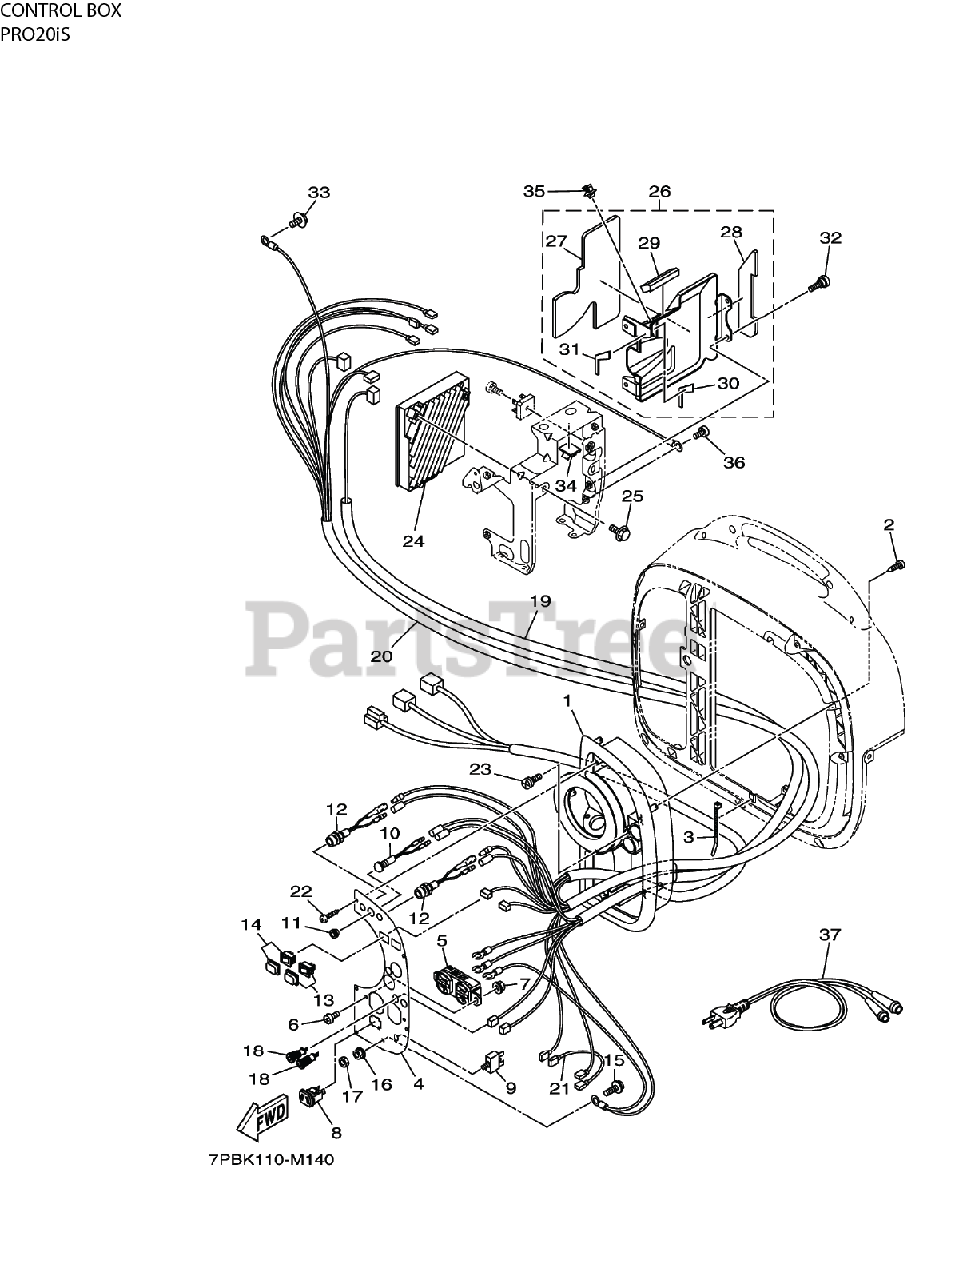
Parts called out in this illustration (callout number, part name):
1	HOUSING - CONTROL BOX COMP
2	SCREW - TAPPING
3	STRAP, CLAMP
4	PANEL, PLATE
5	REED, RECEPTACLE (P&S 5-20R)
6	SCREW - PAN HEAD
7	NUT, FLANGE
8	REED, RECEPTACLE COMP (DC 24V-12A)
9	BREAKER, CIRCUIT COMP (BA)
10	INDICATOR - PILOT LIGHT ASSEMBLY
12	INDICATOR, PILOT LIGHT
13	SWITCH, ENGINE STOP ASSEMBLY
14	SWITCH, ENGINE STOP ASSEMBLY
15	SCREW - BOLT
16	NUT, FLANGE
18	TERMINAL 1
19	HARNESS ASSEMBLY - WIRE
20	LEAD, WIRE
21	LEAD, WIRE 4
22	SCREW - TAPPING
23	SCREW - PAN HEAD
24	ECU, GENSET
25	SCREW - BOLT FLANGE
26	COVER, AIR CLEANER - COVER ASSY 7
29	DAMPER, PLATE
32	PLUG, DRAIN
33	SCREW - BOLT FLANGE
35	CLIP, CLAMP
36	SCREW - PAN HEAD
37	EXTENSION - CHARGE CORD ASSEMBLY
